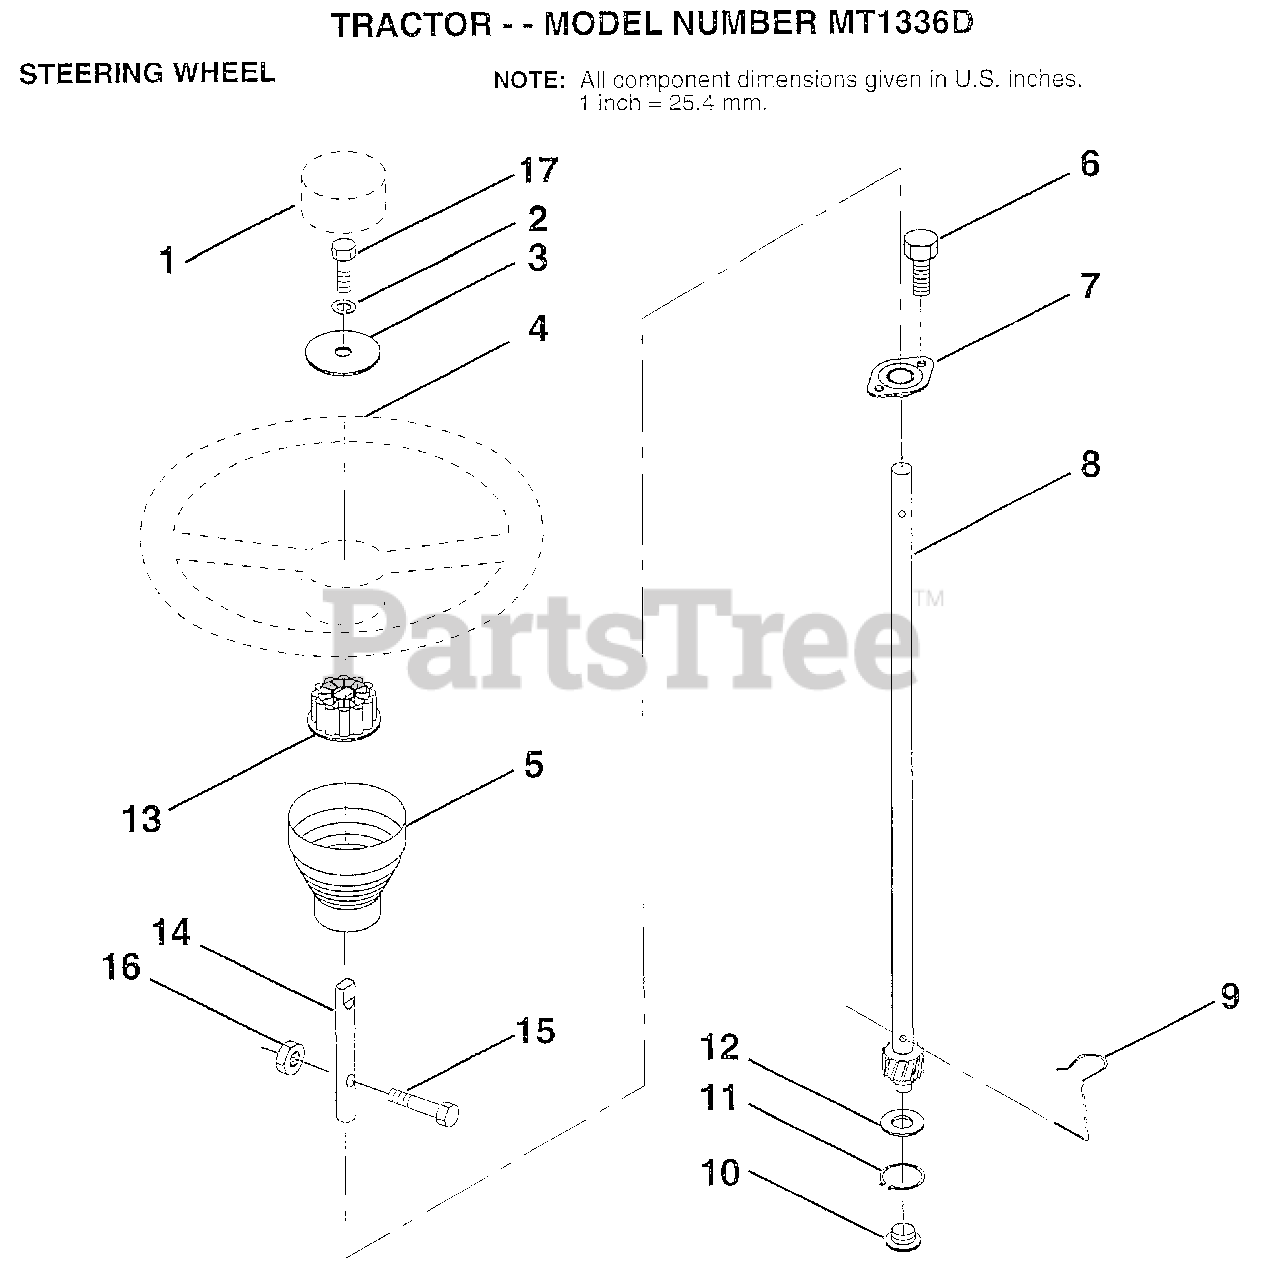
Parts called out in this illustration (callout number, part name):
1	"INSERT,STR WHEEL"
2	LOCKWASHER
3	WASHER T
5	SLEEVE STEERING
6	"SCREW-TT,10-32 FL"
7	BUSHING.STR.623
8	SHAFT.STEERING.LR
9	STEERING CLIP
10	BUSHING STEER LWR
11	RING
12	WASHER LT
13	ADAPTOR, STEERING WHEEL
14	EXT SHAFT STEERIN
15	BOLT
16	NUT
17	BOLT
